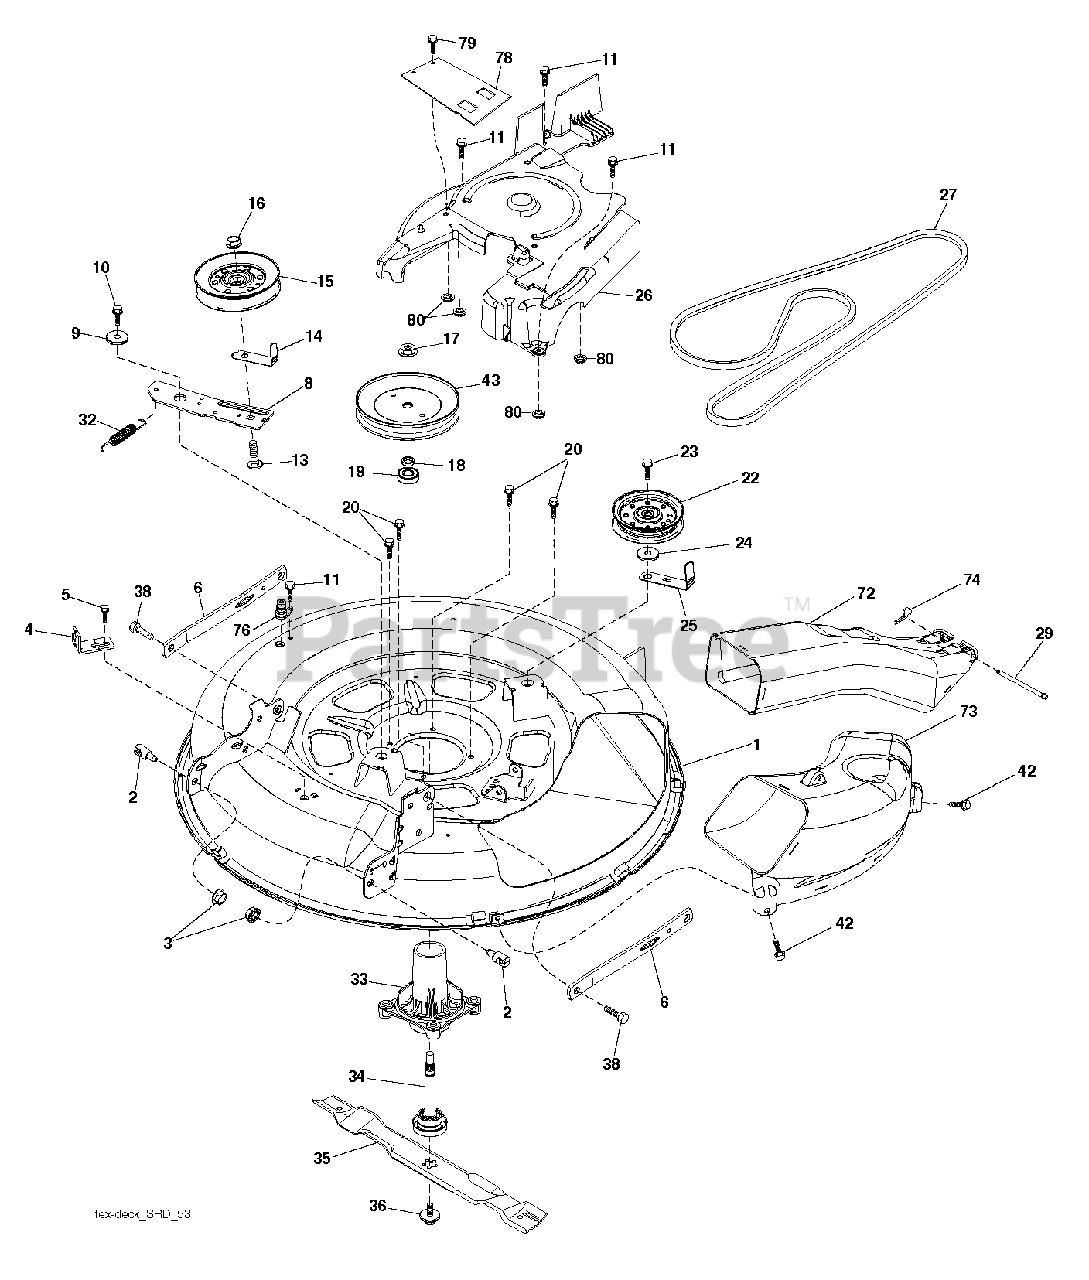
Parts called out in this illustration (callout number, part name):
1	DECK.WELDMENT.PNT.30"SRD
2	STUD.FASTNER.W/ANTI-ROTATE
3	NUT LOCK HEX FLANGE 5/16-18
4	BRACKET.CLUTCH.CABLE
5	BOLT.5/16HEX.WHS.HD
6	ARMS.SUSP.MOWER.REAR.SRD
8	ARM.IDLER.30"SRD
9	SPACER.RETAINER
10	SCREW 3/8-16X1
11	SCREW.1/4-20X5/8
13	BOLT.3/8-16X1.50
14	KEEPER, BELT IDLER
15	PULLEY.IDLER.4.25
16	NUT LOCK FLG 3/8-16 UNC
17	NUT.FLANGE.LOCK.TOP
18	WASHER.SPACER.MANDREL
20	SCREW, WASHER HEAD
22	PULLEY.IDLER.FLAT.46.PR.DR.
23	SCREW LT
24	WASHER
25	KEEPER.BELT.30"SRD
26	COVER.ASM.MANDREL.30"
27	V-BELT.DRIVE.MOWER.30"
29	PIN.HINGE.30".SRD
32	SPRING.MOWER.DRIVE.ELECTRIC
33	HOUSING.MANDREL.4PT.
34	SHAFT.ASM.MDRL.N/GREASE.38
35	BLADE.MOWER.BAGGING.30"
36	BOLT.WASHER.ASM.7/16-2
38	BOLT.SHOULDER
42	SCREW, 3/8-16X3/4
43	PULLEY, MANDREL 6.5 PD
72	CHUTE.UPPER.SRD.30R"
73	CHUTE.LOWER.SRD.30R"
74	Retainer Spring
76	PORT.WASHOUT
78	GUARD ARM CLUTCH
79	SCREW.HI-LO.CONSOLE
80	PALNUT 1/4
